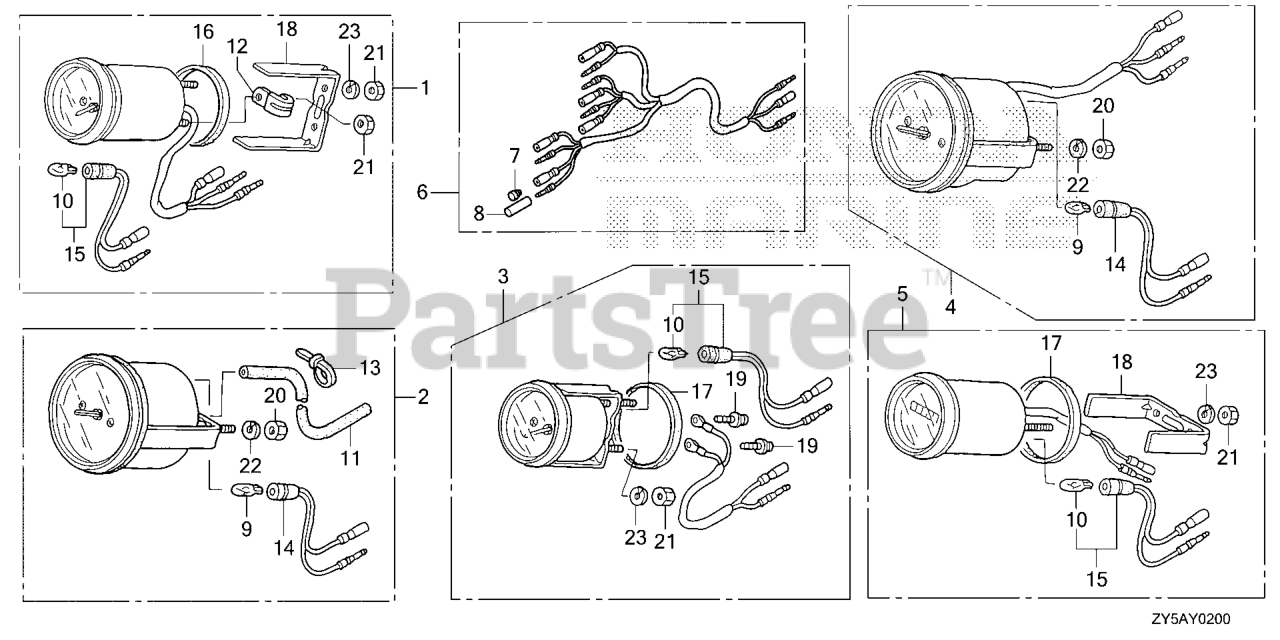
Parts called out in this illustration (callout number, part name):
1	METER KIT, TRIM (WHITE)
1	METER KIT, TRIM (B) (BLACK)
2	SPEEDOMETER KIT (WHITE)
2	SPEEDOMETER KIT *NHA85* (B) (BLACK)
3	METER KIT, VOLT (WHITE)
3	METER KIT, VOLT *NHA85* (B) (BLACK)
4	METER KIT, TACHO
4	METER KIT, TACHO (B)
5	METER KIT, HOUR (WHITE) (NA USE ALT:39700-ZW5-000ZA)
5	METER KIT, HOUR (B) (NA USE ALT:39700-ZW5-000ZA)
6	HARNESS ASSY., METER (B)
7	PLUG, CONNECTOR (INNER) (TROLLING CONTROL)
8	PLUG, CONNECTOR (OUTER) (ENGINE NO.)
9	BULB, WEDGE BASE (T10) (12V 1.7W) (STANLEY)
10	BULB, WEDGE BASE (12V1.7W) (TOSHIBA)
11	TUBE, SPEED METER (4X7X8000)
12	CLAMP
13	BAND, SELF-LOCK
15	SOCKET
16	GASKET (TO 1015209) (FROM 1015210)
17	GASKET
18	BRACKET (TO 1015209) (FROM 1015210)
19	SCREW-WASHER (3X22)
21	NUT, HEX. (4MM)
23	WASHER, SPRING (4MM)
